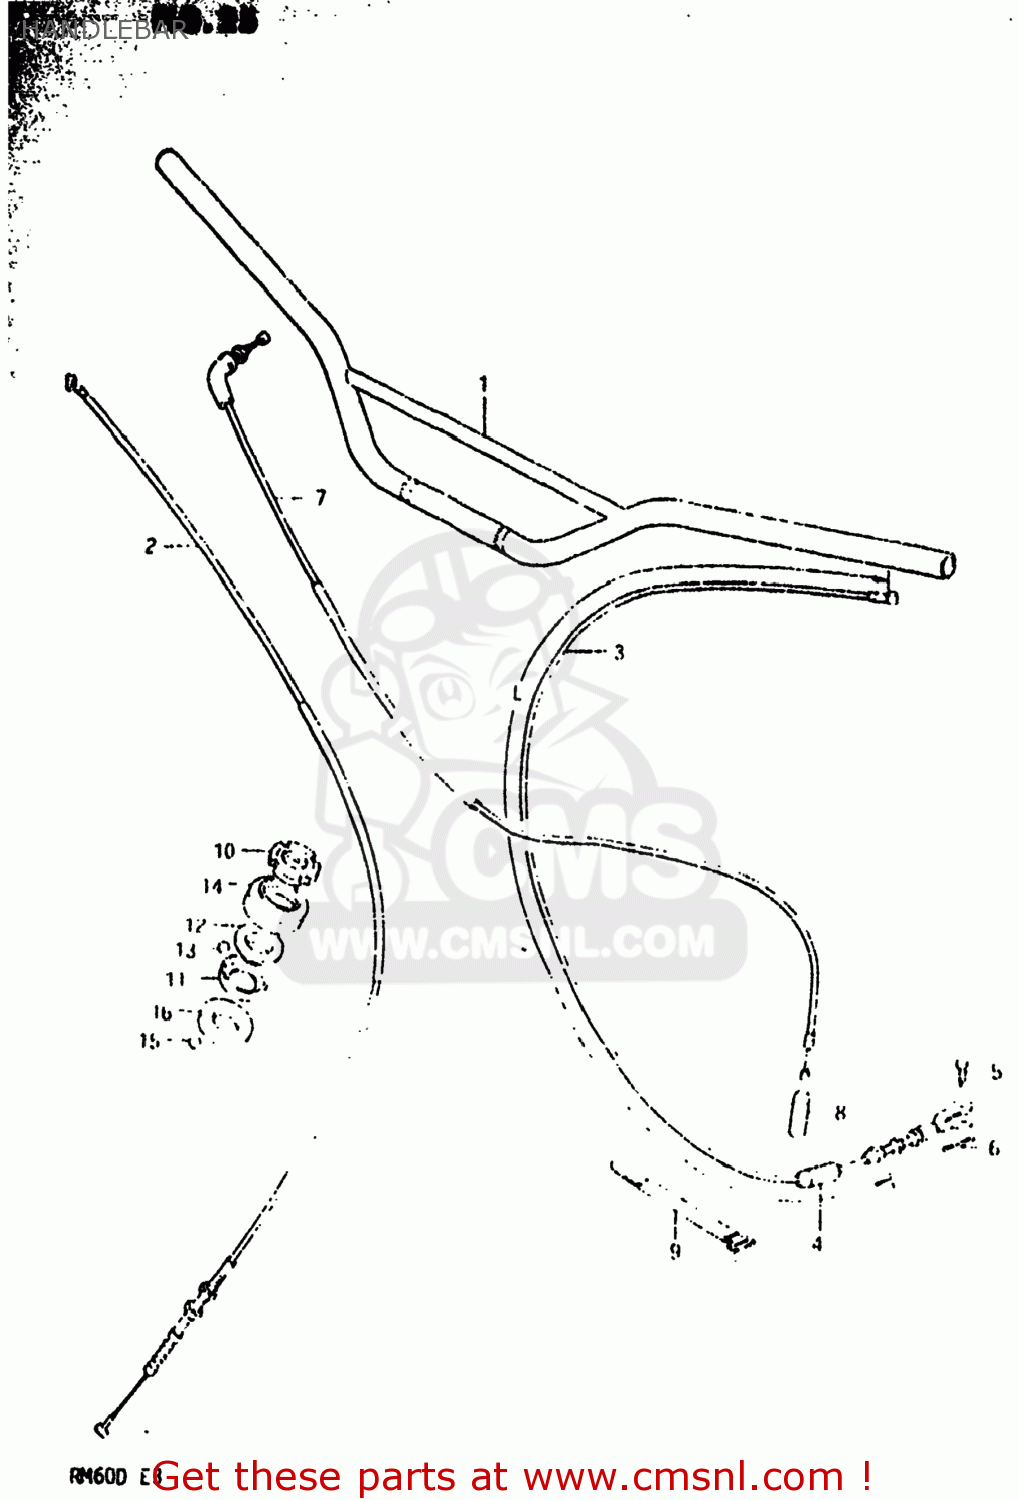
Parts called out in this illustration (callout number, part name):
1	HANDLEBAR
2	CABLE,FRONT BRAKE
3	CABLE ASSY,CLUTCH
4	SEAL,DUST(7X18X30)
5	PIN(L:13)
6	PIN
7	CABLE ASSEMBLY,THROTTLE
8	SEAL,DUST(7X18X30)
9	CLAMP
10	NUT,STEERING STEM(25X44X10)
11	RACE,STEERING INNER UPR
12	RACE,STEERING OUTER UPR
13	BALL
14	DUST SEAL,STEERING UPR
15	BALL
16	LACE,STEERING INNER LWR
